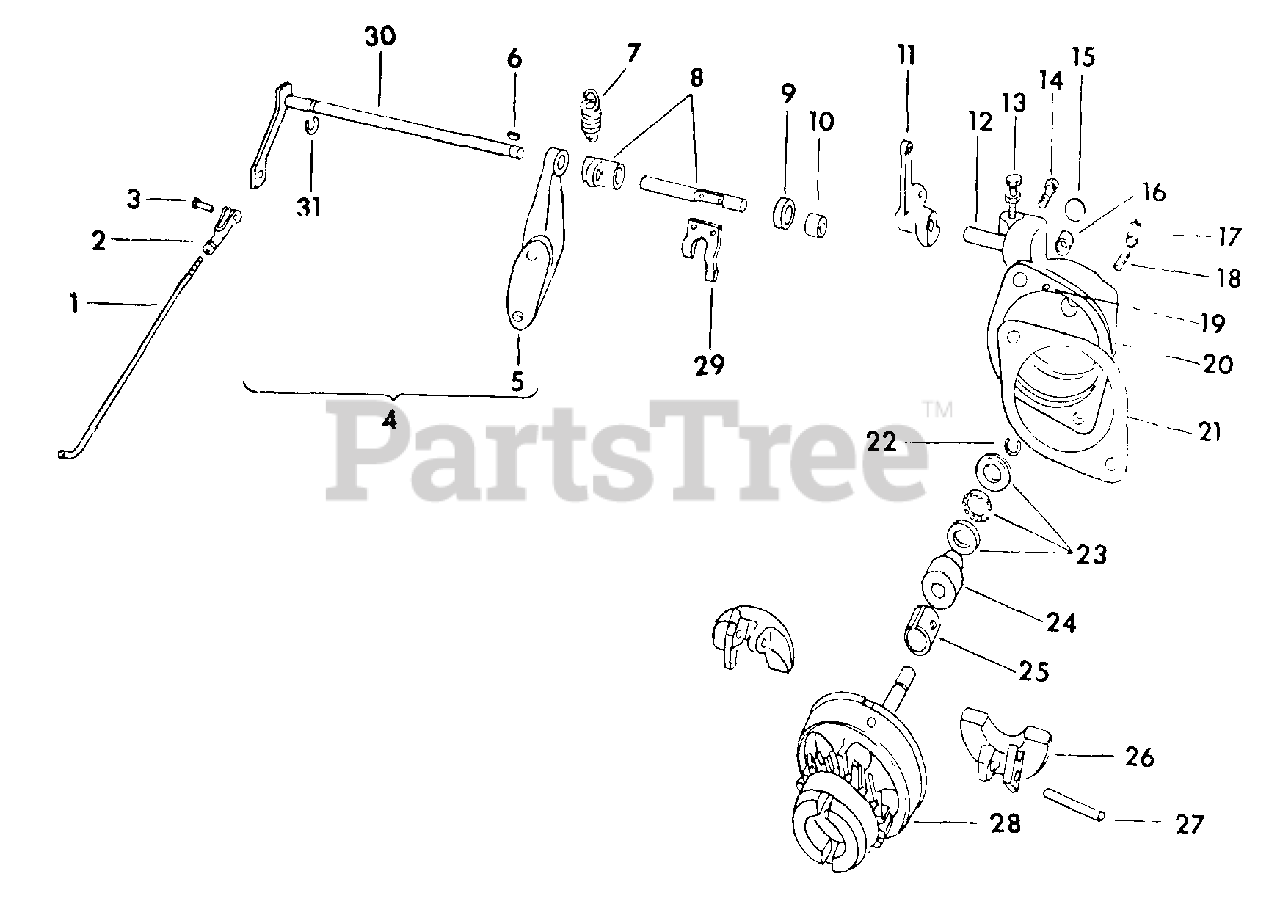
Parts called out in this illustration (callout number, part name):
1	ROD, GOVERNOR CONNECTING
2	CLEVIS, 10-32 SHORT ADJ ROD END
3	PIN, 3/16 X 19/32 ROD END
4	EXTENSION ASSY, GOVERNOR ROCKSHAFT AND BRACKET
5	BRACKET, GOVERNOR ROCKSHAFT EXTENSION
6	KEY, 3/32 X 1/2 WOODRUFF
7	SPRING, GOVERNOR
8	ROCKSHAFT ASSY, GOVERNOR AND SPRING LEVER
9	SEAL, GOVERNOR ROCKSHAFT OIL
10	BEARING, GOVERNOR ROCKSHAFT
11	LEVER, GOVERNOR SPRING THROTTLE
12	SHAFT, GOVERNOR THROTTLE LEVER
13	SCREW, GOVERNOR SPEED CHANGE LEVER STOP
15	PLUG, 5/8 EXPANSION
16	BUSHING, GOVERNOR SHAFT
17	BODY, GOVERNOR BUMPER SPRING
18	SPRING, GOVERNOR BUMPER
19	PIN, GOVERNOR BASE DOWEL
20	HOUSING ASSY, GOVERNOR
21	GASKET, GOVERNOR HOUSING
22	RING, GOVERNOR SLEEVE STOP
23	BEARING, GOVERNOR THRUST BALL
24	SLEEVE, GOVERNOR THRUST
25	BUSHING, GOVERNOR BASE
26	WEIGHT, GOVERNOR
27	PIN, GOVERNOR WEIGHT
28	SHAFT, GOVERNOR W/CARRIER AND PIN
28	SHAFT GOVERNOR W/CARRIER AND PIN
29	FORK, GOVERNOR TENSION
30	EXTENSION ASSY, GOVERNOR ROCKSHAFT
31	RING, GOVERNOR ROCKSHAFT EXTENSION STOP
